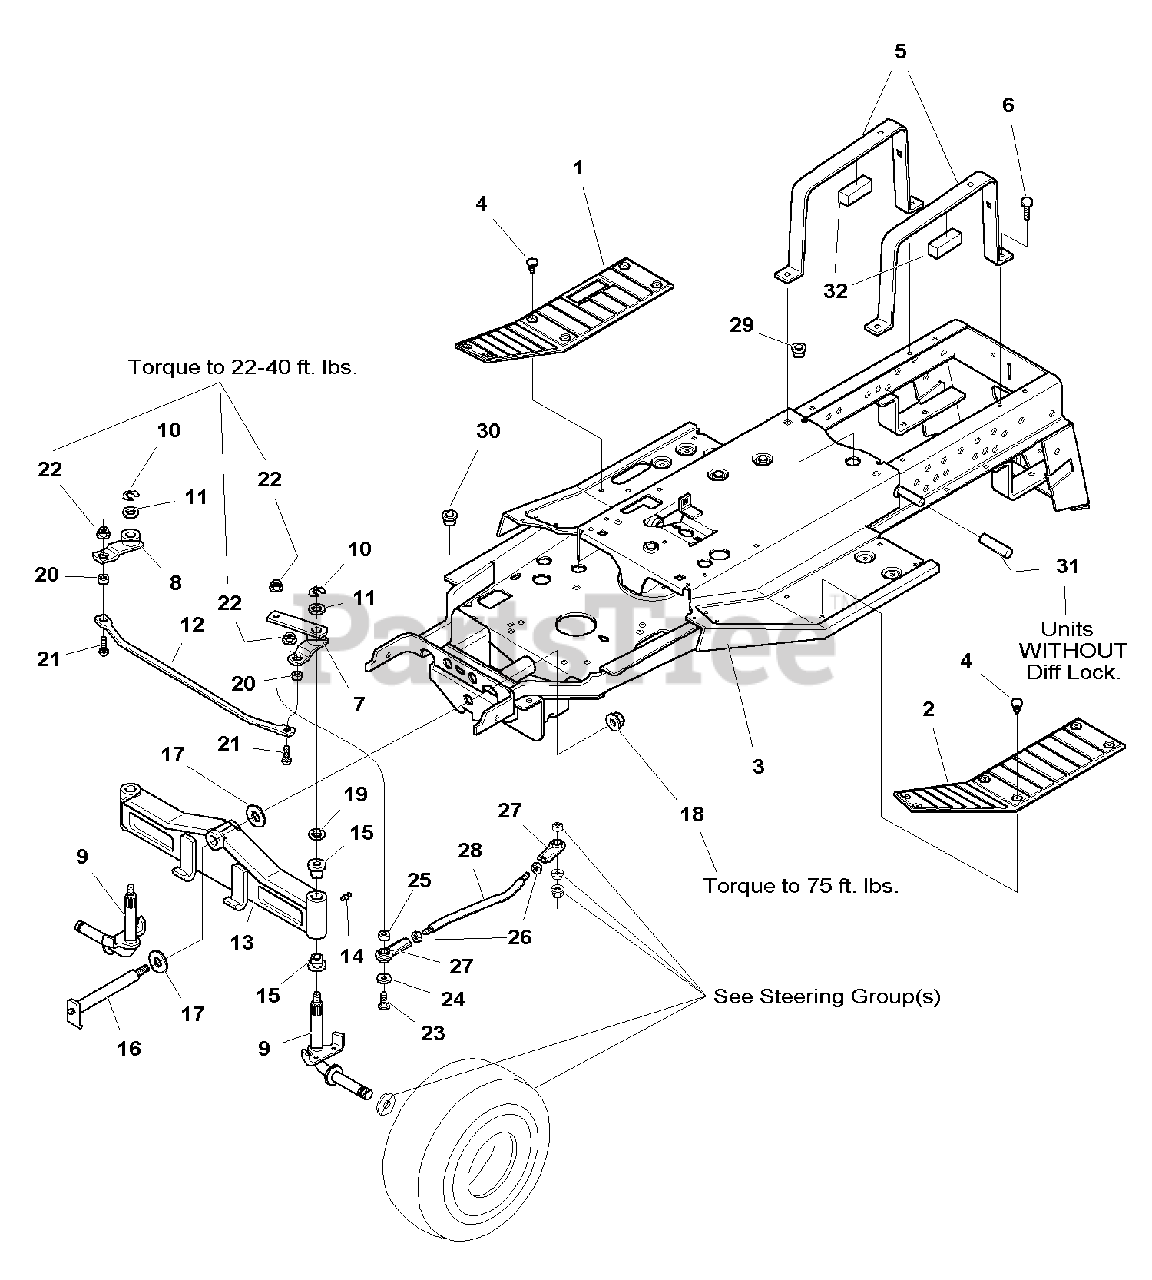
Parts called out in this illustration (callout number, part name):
1	PAD, Footrest, RH
2	PAD, Footrest, LH
3	FRAME ASSEMBLY (Air-Cooled Models)
3	FRAME ASSEMBLY (Liquid-Cooled Models)
4	FASTENER, Panel
5	STRAP, Fuel Tank
6	CAPSCREW, Hex Head, Taptite, 5/16-18 X 1
7	STEERING ARM ASSEMBLY, LH, Splined
8	STEERING ARM ASSEMBLY, RH, Splined
9	SPINDLE ASSEMBLY
10	KLIP RING, 5/8
11	WASHER, 5/8
13	AXLE ASSEMBLY, Front
14	FITTING, Grease, 1/4
16	AXLE PIVOT ASSEMBLY
17	WASHER, Special, 1.0
18	NUT, Hex Full, Lock, 3/4-16
19	WASHER, Plain, 3/4
21	CARRIAGE BOLT, 3/8-16 x 1
22	NUT, Hex Flange, 2-Way Lock, 3/8-16
23	CAPSCREW, Hex Head, 3/8-16 x 1-3/8
24	WASHER, Plain, 3/8
26	NUT, Hex Jam, 1/2-20
27	BALL JOINT, Flat
29	BUSHING, Snap
30	BUSHING, Snap, Large
31	GRIP, Plastic (Units without Diff. Lock)
32	FOAM
